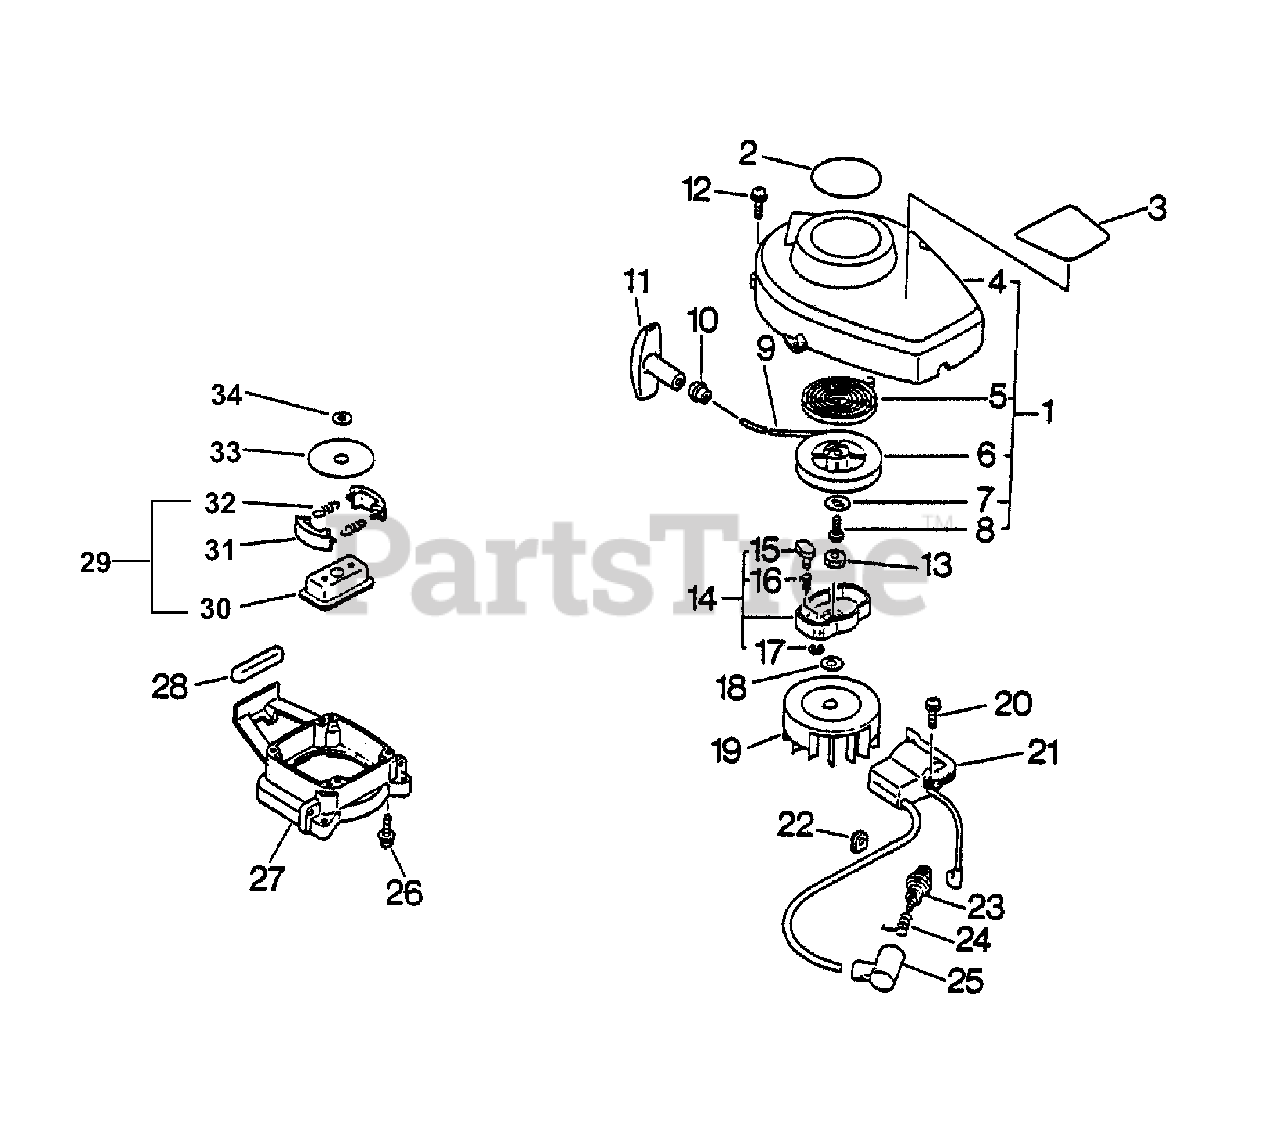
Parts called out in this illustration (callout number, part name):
1	STARTER ASSY
2	LABEL, ECHO
3	LABEL, HC-2100
4	CASE, STARTER
5	SPRING, REWIND
6	REEL, ROPE
7	WASHER
9	ROPE, STARTER
10	GUIDE, ROPE
11	GRIP, STARTER
12	SCREW 4×16
14	STARTER PAWL ASSY
15	PAWL, STARTER
16	SPRING, RETURN
17	E-RING 4
18	WASHER 8.5×16×1.2
19	FLYWHEEL
20	SCREW 4×22
21	COIL, IGNITION
23	SPARK PLUG - BPM7A
23	SPARK PLUG - RCJ7Y
24	TERMINAL, SPARK PLUG
25	CAP, SPARK PLUG
26	SCREW 4×16
27	CASE, CLUTCH
28	CUSHION, FUEL TANK
29	CLUTCH ASSY
30	HUB, CLUTCH
31	SHOE, CLUTCH
32	SPRING, CLUTCH
33	PLATE, CLUTCH
34	WASHER, CLUTCH
